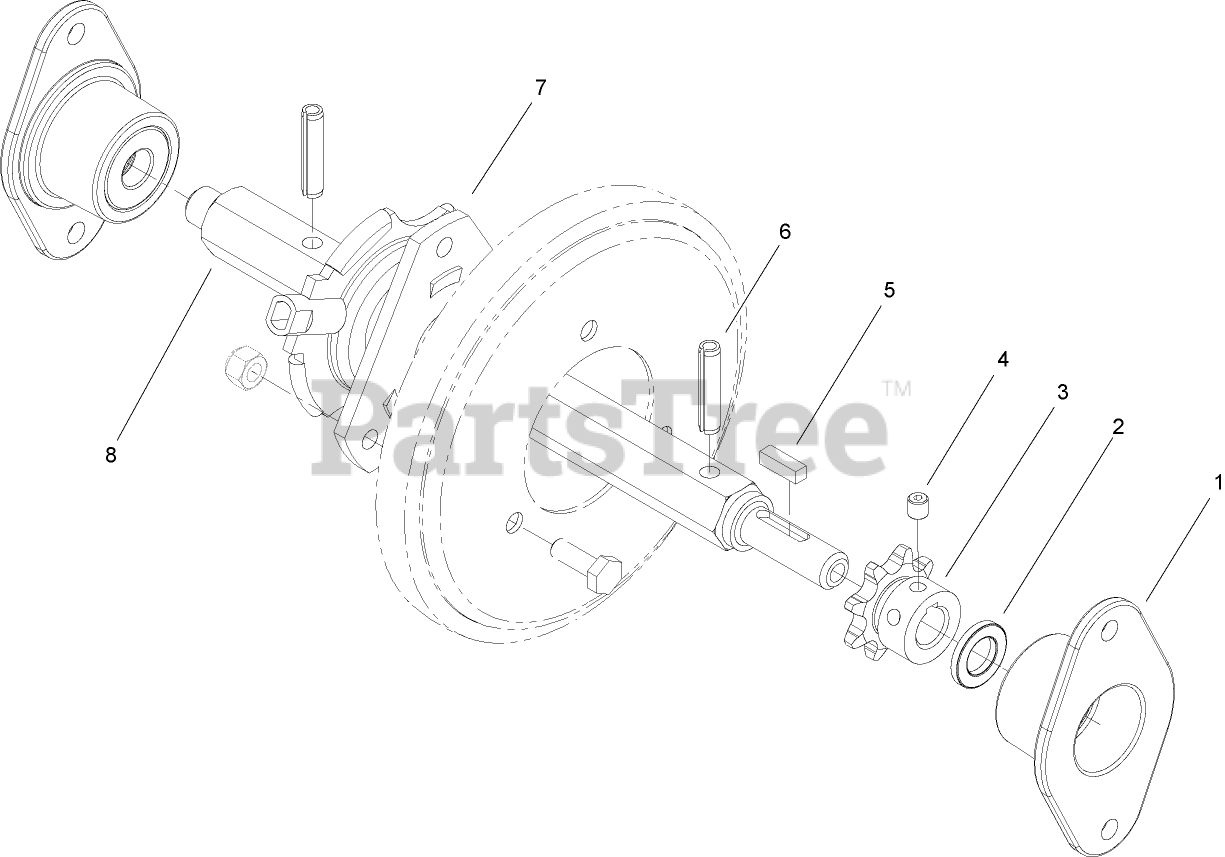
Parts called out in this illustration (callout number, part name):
1	RETAINER-BEARING
2	SPACER-BUSHING
3	SPROCKET-8 TOOTH
4	SCREW-HSH
5	KEY-SQUARE
6	PIN-ROLL, SLOTTED
7	TRUNNION-HEX
8	SHAFT-HEX
